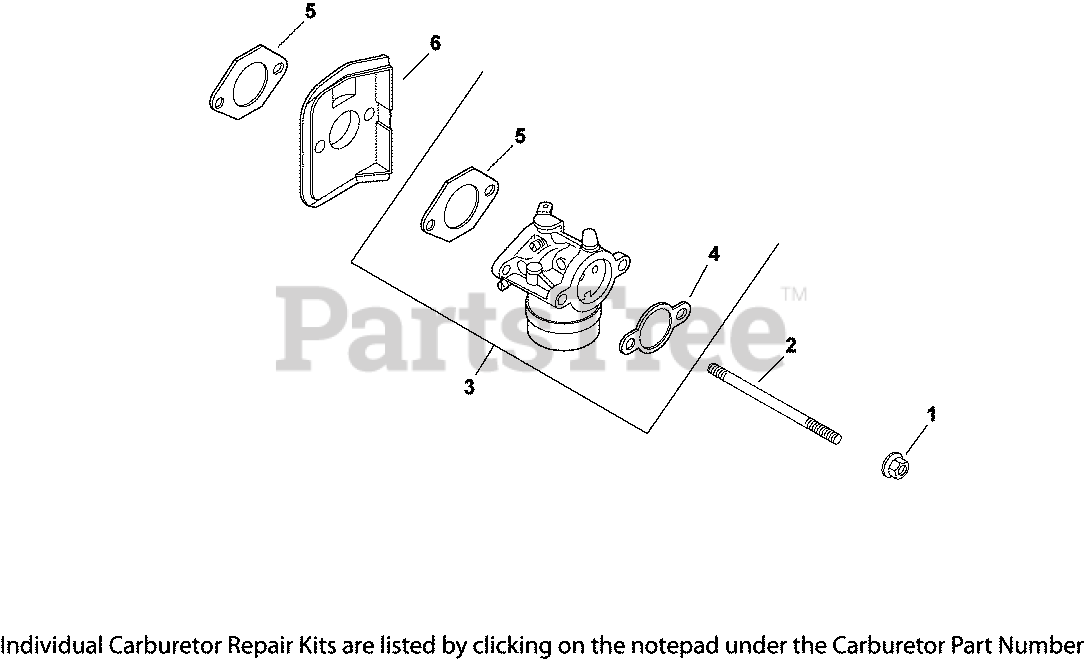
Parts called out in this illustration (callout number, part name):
1	NUT, FLG M6X1.0
2	STUD,M6X1.0X116
3	KIT, CARBURETOR w/GASKETS
4	GASKET, AIR CLEANER BASE
5	GASKET, CARBURETOR
6	DEFLECTOR, HEAT
